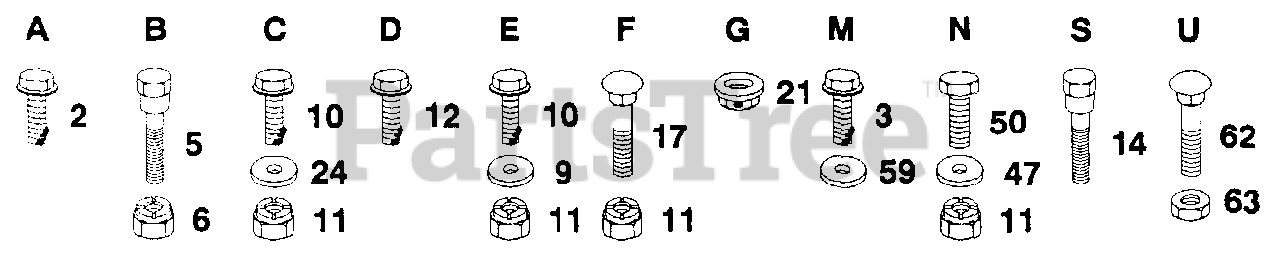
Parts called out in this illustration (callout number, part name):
2	SCREW
3	SCREW GTV
9	WASHER
12	SCREW LT
14	"BOLT,SHOULDER"
17	BOLT
21	PAL NUT LT
24	WASHER
47	WASHER
50	BOLT
59	WASHER
62	BOLT
